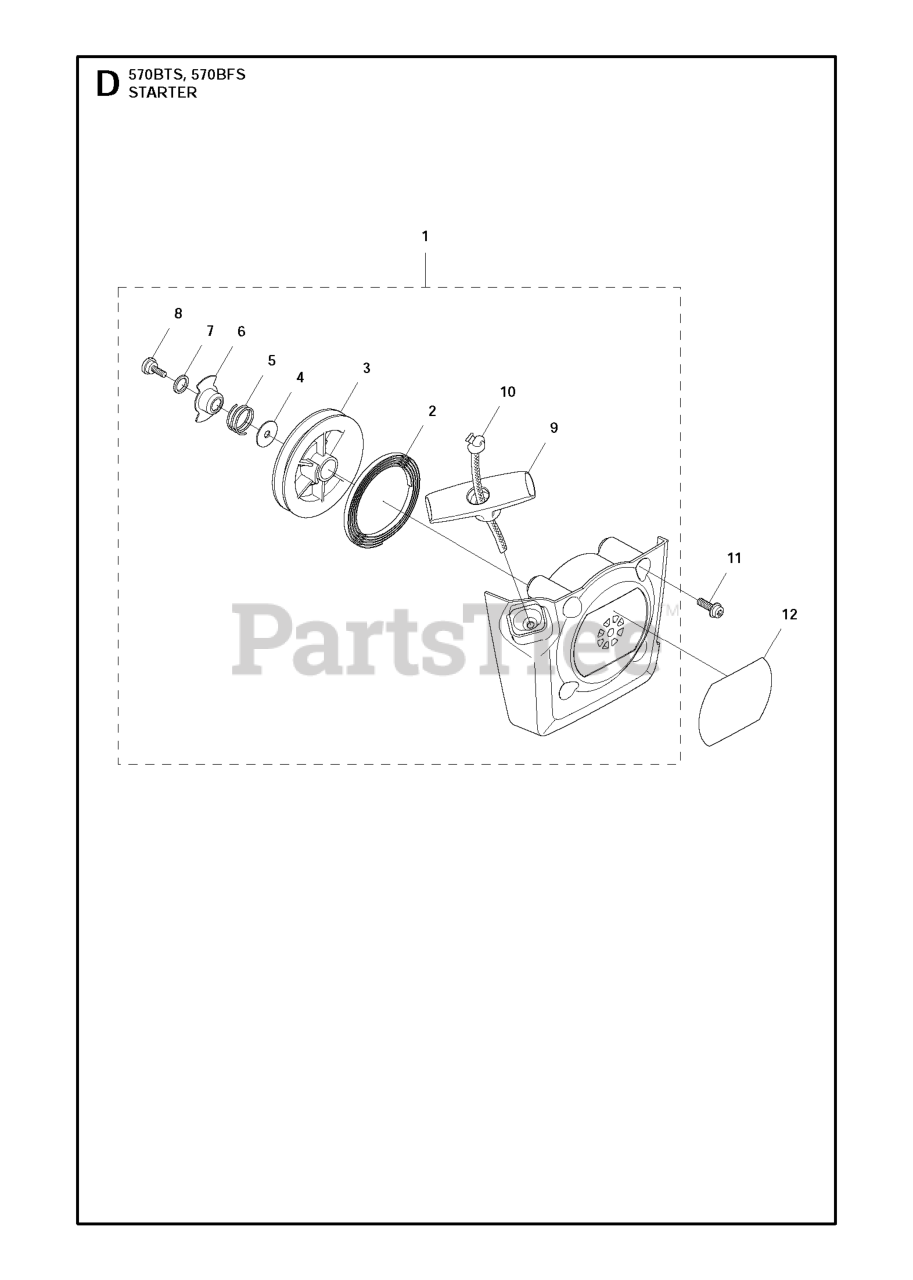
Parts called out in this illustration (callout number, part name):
1	STARTER ASSY
4	WASHER
5	SPRING FRICTION
12	Decals
12	DECAL STARTER
